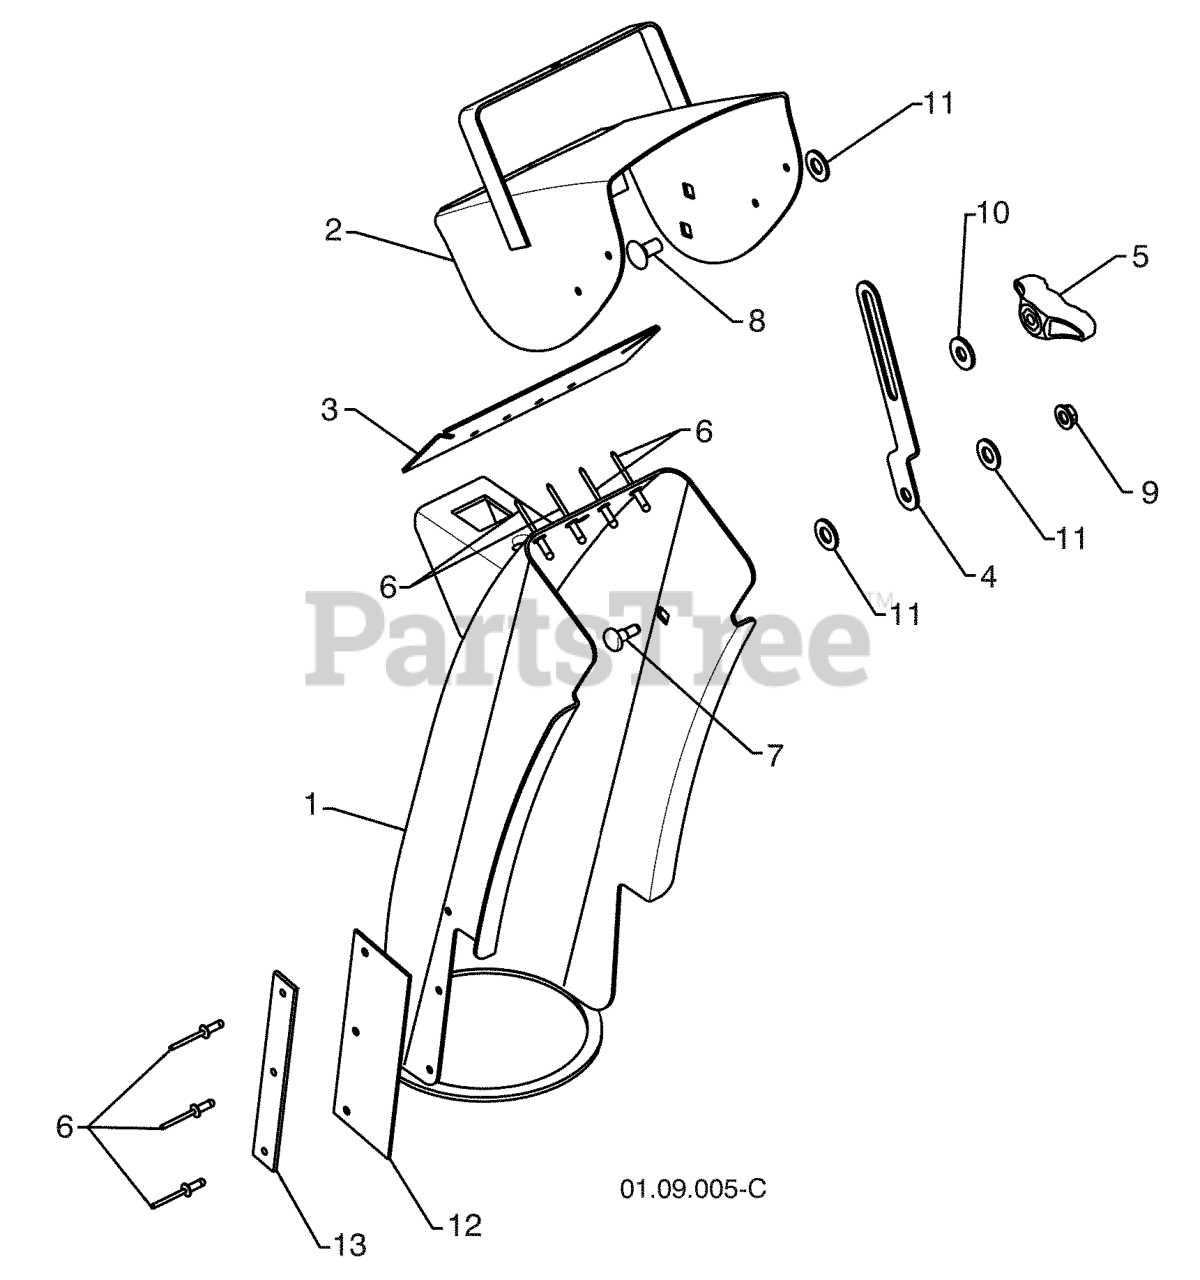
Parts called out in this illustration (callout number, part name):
1	CHUTE.WELDMENT
2	DEFLECTOR.WELDMENT.PNT.ORANGE
3	SEAL.DEFLECTOR
4	STRAP, CHUTE
5	KNOB, DEFLECTOR
6	RIVET BLIND
7	SHOULDER BOLT
8	BOLT
9	NUT.HEX.FLANGE.1/4
10	WASHER.20X8.5
11	WASHER, NYLON FRICTION
12	SHIELD.SNOW.CHUTE
13	STRAP.SHEILD.RETAINER
